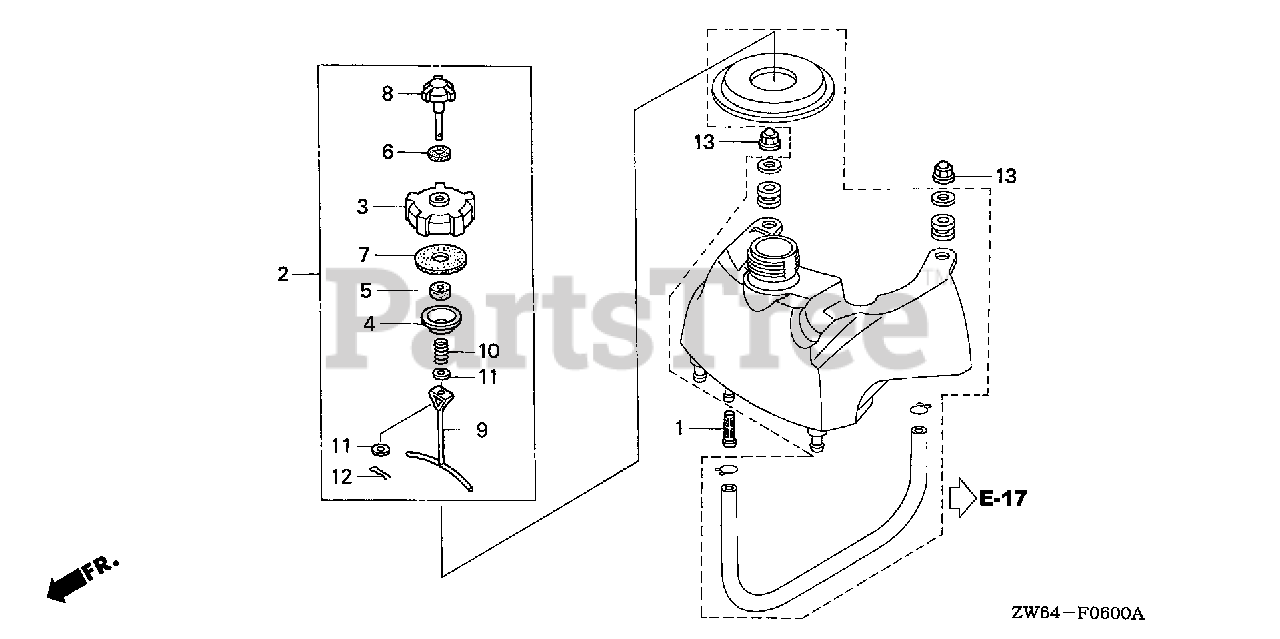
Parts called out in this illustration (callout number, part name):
1	FILTER, FUEL
2	CAP ASSY., FUEL TANK
3	BODY, FUEL CAP
4	INNER, FUEL CAP
5	SPONGE, FUEL CAP BREATHER
6	GASKET, VALVE
7	GASKET, FUEL CAP
8	VALVE, BREATHER
9	LINK, FUEL CAP
10	SPRING, FUEL CAP
11	WASHER, PLAIN (4MM)
12	PIN, LOCK (4MM)
13	NUT, CAP (6MM)
